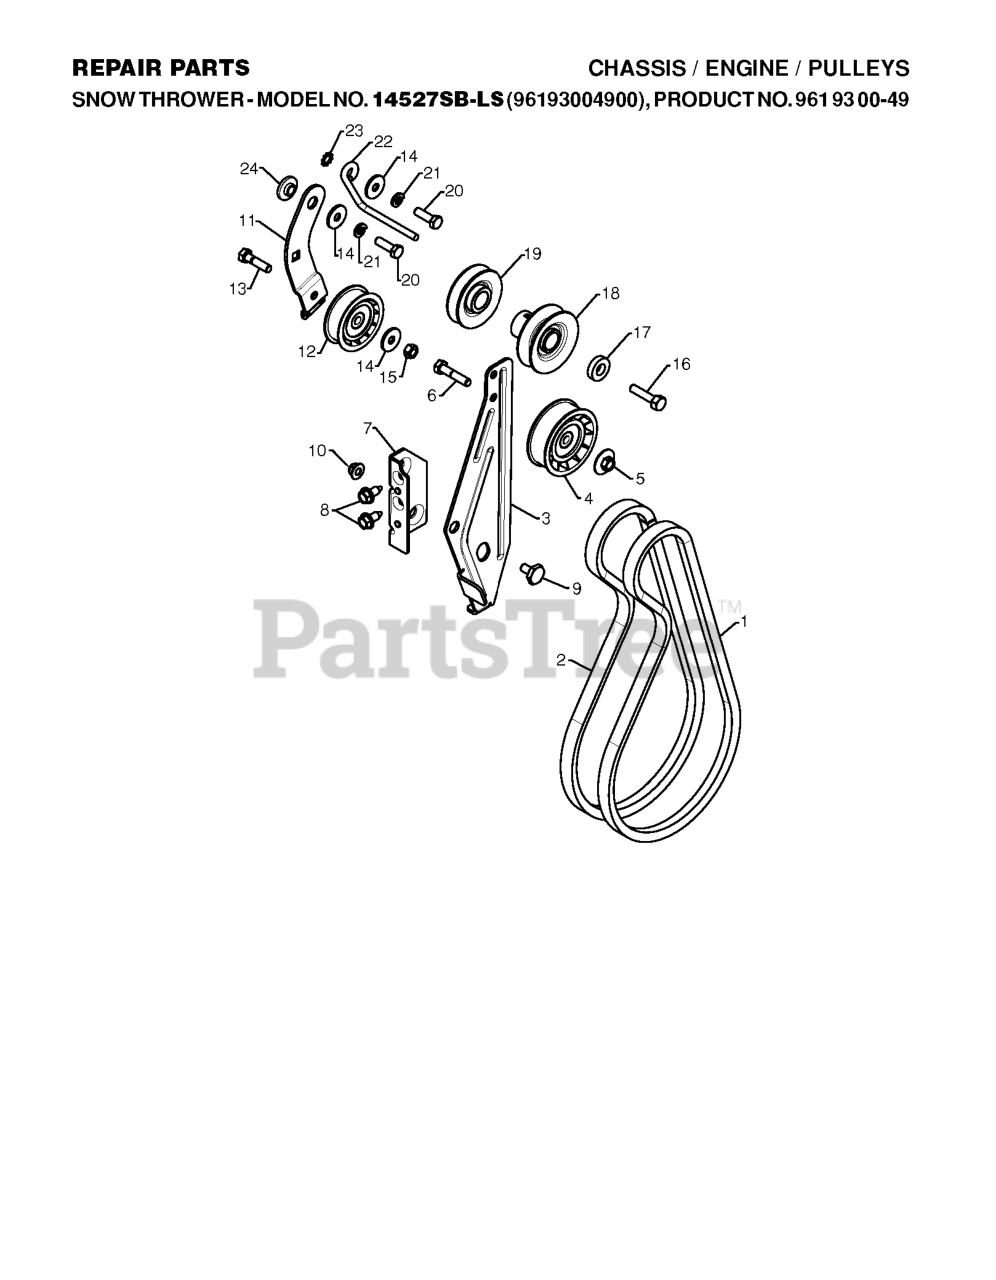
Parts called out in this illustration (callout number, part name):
1	BELT.V.IMPELLER
2	V-BELT TRACTION 34.25
3	ARM.IDLER.BRAKE
4	PULLEY.W/SPACER.2.75
5	NUT.FLANGE.HEX.5/16X18.BLACK
6	HEX BOLT
7	RP BRACKET.IDLER
8	BOLT.HEX.HD.WASHER.5/16-18X.75
9	BOLT.SHOULDER.1/2X12
10	NUT.LOCK.5/16-18
11	ARM, IDLER
12	PULLEY.W/SPACER.2.25
13	BOLT.5/16-18X1-1/4 FULL.THREAD
14	STEEL WASHER
15	NUT.71038.31-18.HEX.NYLOCK
16	SCREW, HEX HD 3/8-24 X 1-3/8
17	WASHER, FLAT 3/8
18	PULLEY.IMPELER.
19	PULLEY.ENG.TRACTION
21	WASHER.LOCK.HVY.HLCL.SPR.5/16
22	BELT.GUIDE.RH
23	WASHER EXT TOOTH LOCK 5/16
24	RP BUSHING, IDLER PIVOT
